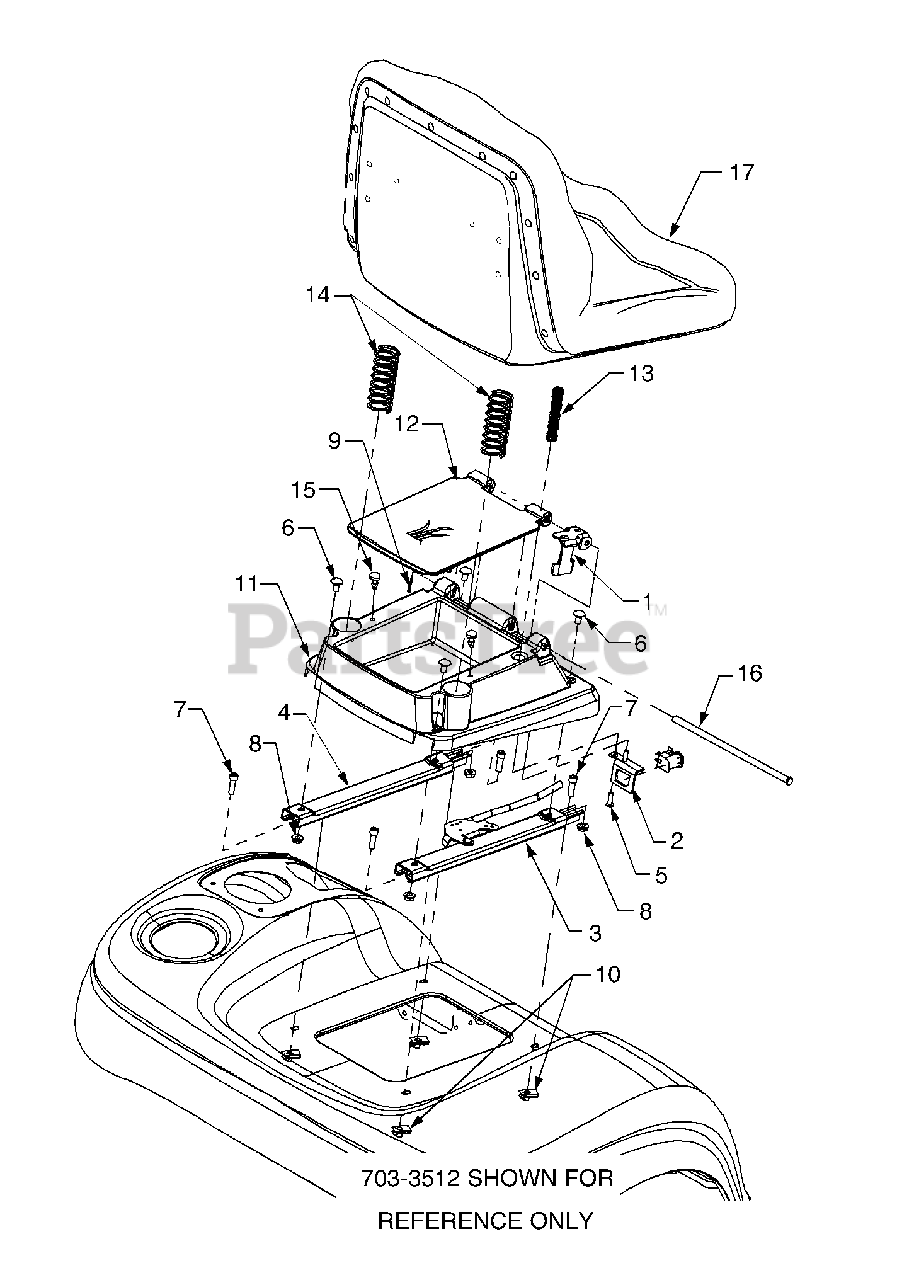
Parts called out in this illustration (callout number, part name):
1	Bracket, Seat Switch
2	Bracket, Switch Mounting
3	Track, Seat, w/Latch
4	Track, Seat, w/o Latch
5	Screw, Pan Torx Hd., #12-14 x .5
6	Carriage Bolt, 5/16-18 x .62
7	Screw, Pan Torx Hd. 5/16-18 x 1.0
8	Nut, Hex Flange Lock, 5/16-18
9	Pin, Cotter, 3/32 x .75
10	Speed Nut, U-Type, 5/16-18
11	Base, Seat
12	Lid, Tlbx
13	Spring, Compression
14	Spring, Compression
15	Bumper
16	Rod, Seat Pivot
17	Seat, High Back
